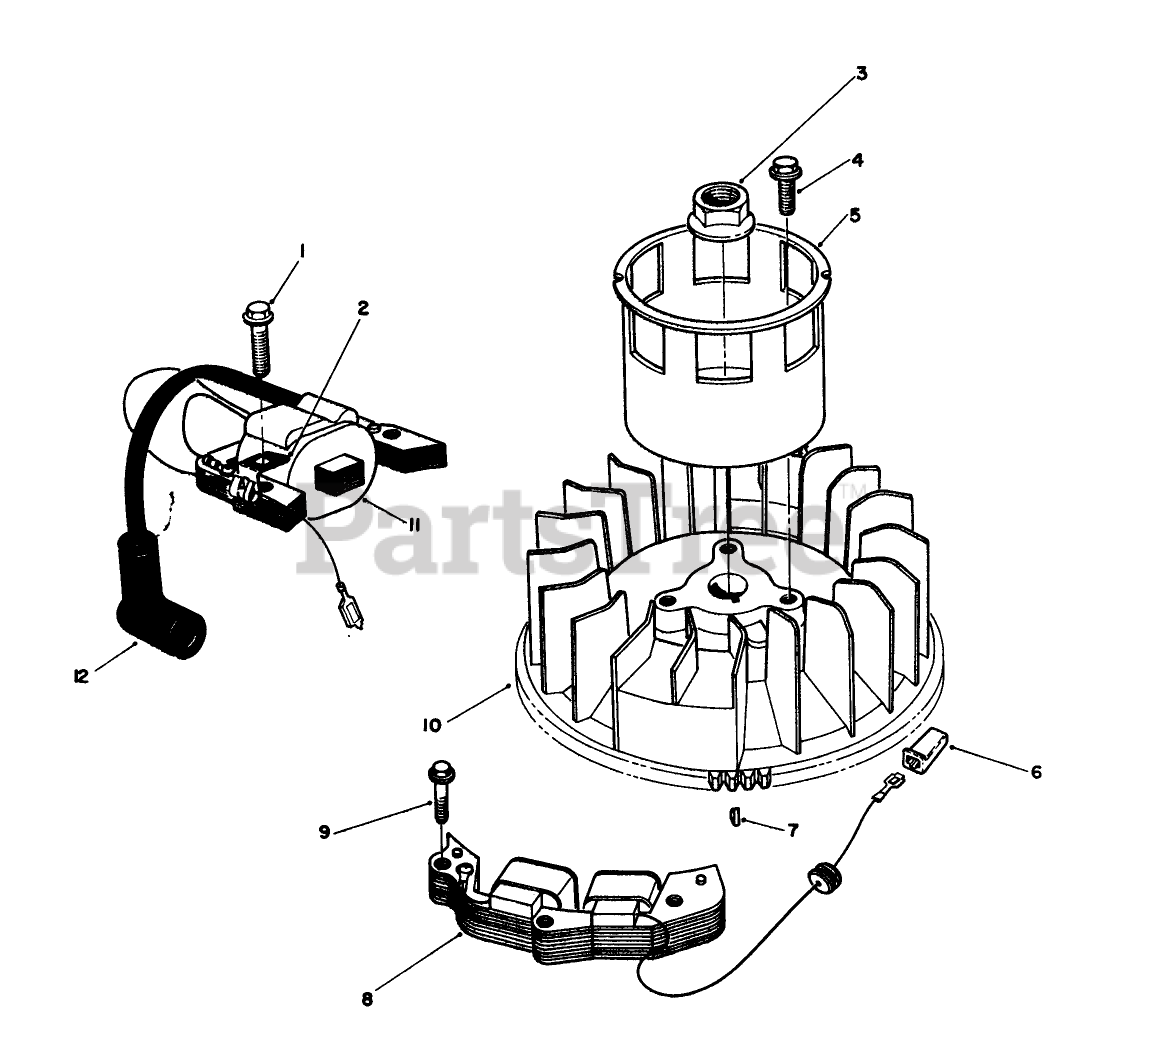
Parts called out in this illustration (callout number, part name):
2	CLAMP
6	CONNECTOR BODY
10	FLYWHEEL
11	COIL ASM
12	COVER
